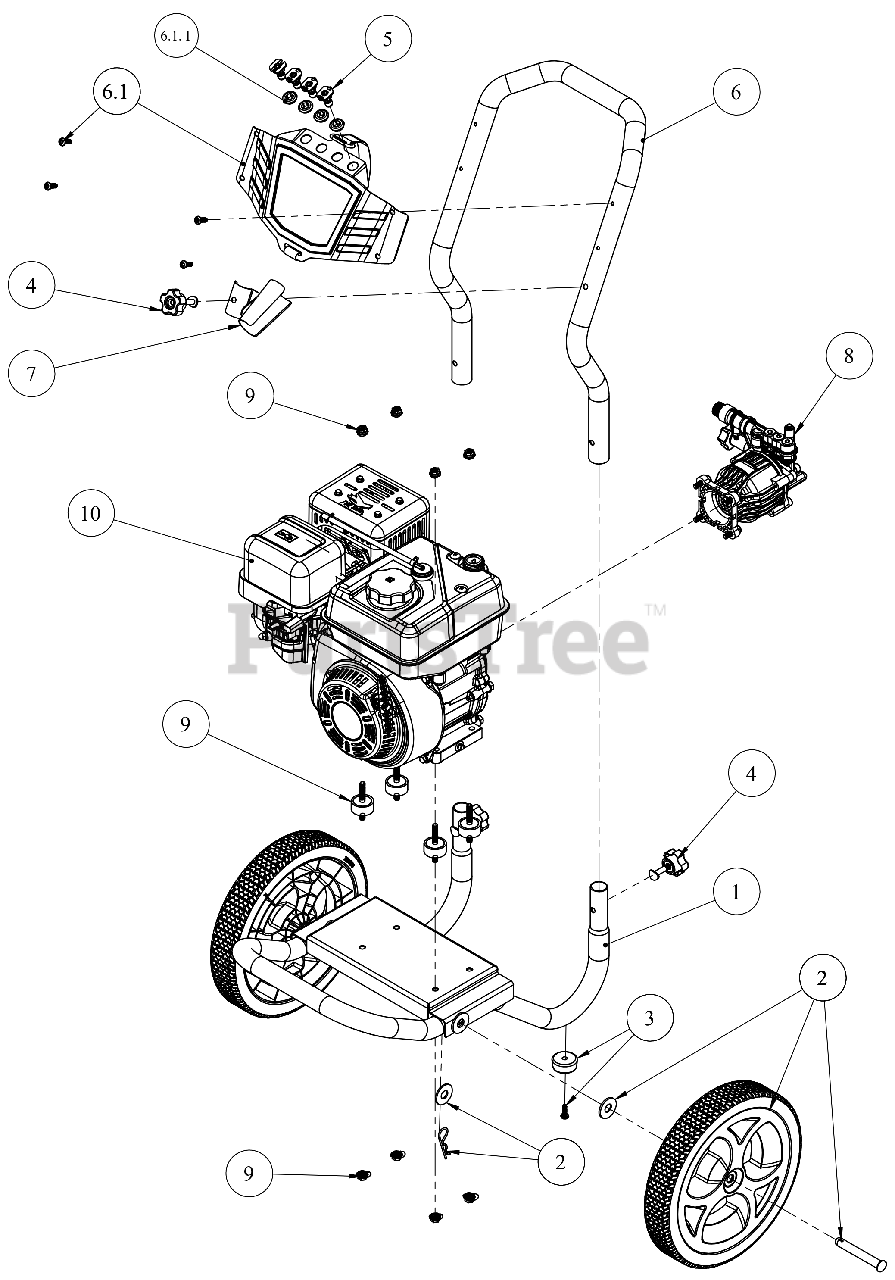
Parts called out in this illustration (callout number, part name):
1	FRAME BASE (YELLOW)
2	WHEEL KIT-12"
4	KNOB-HANDLE MTG
5	4 PIECE NOZZLE SET
6	UPPER HANDLE (YELLOW)
6.1	DASH BOARD PANEL (W/LBL) (PW3024)
6.1.1	SPRAY NOZZLE HOLDER
7	SPRAY GUN HOLDER
8	PUMP (SVC 520006)
9	ENGINE MTG KIT
10	COMPLETE ENGINE 208cc
